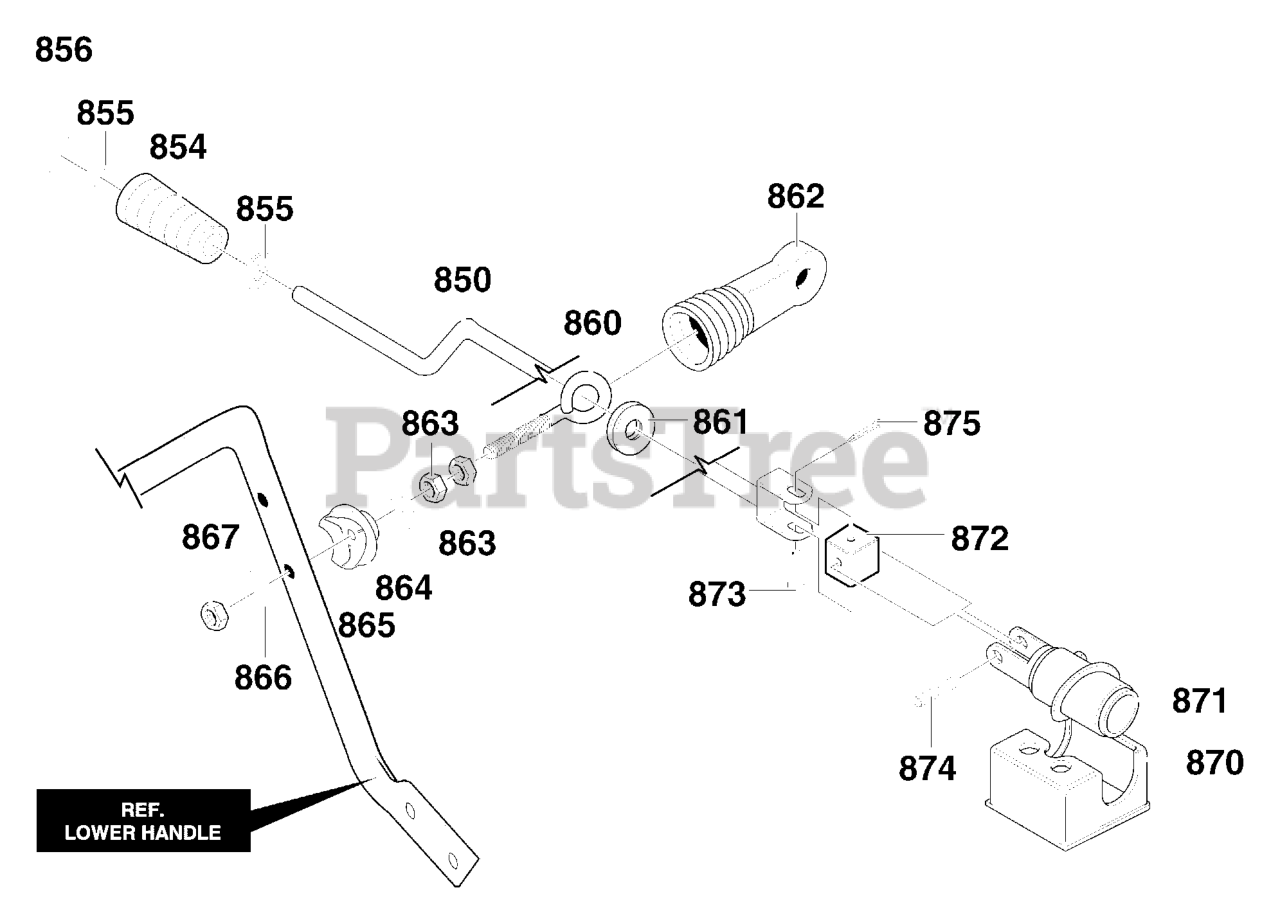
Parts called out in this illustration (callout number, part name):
850	CRANK, ASSY CHUTE
854	HANDLE, CHUTE CRANK
855	FLATWASHER .39X.70X.05
860	EYE BOLT 3/8-16X6.00
861	GROMMET, EYE BOLT
862	BOOT
863	NUT, 3/8-16 HEXJAM
864	FLATWASHER .406X.81X.066
865	ADAPTER, BOOT TO HANDLE
866	FLATWASHER .406X.81X.066
867	NUT, 3/8-16 HEXNYL
870	BRACKET, WORM MTG
871	WORM, GEAR CHUTE ROTATION
872	BLOCK, UNIVERSAL PIVOT
873	CLEVIS PIN
874	PIN, UNIVERSAL JOINT
875	COTTER PIN
